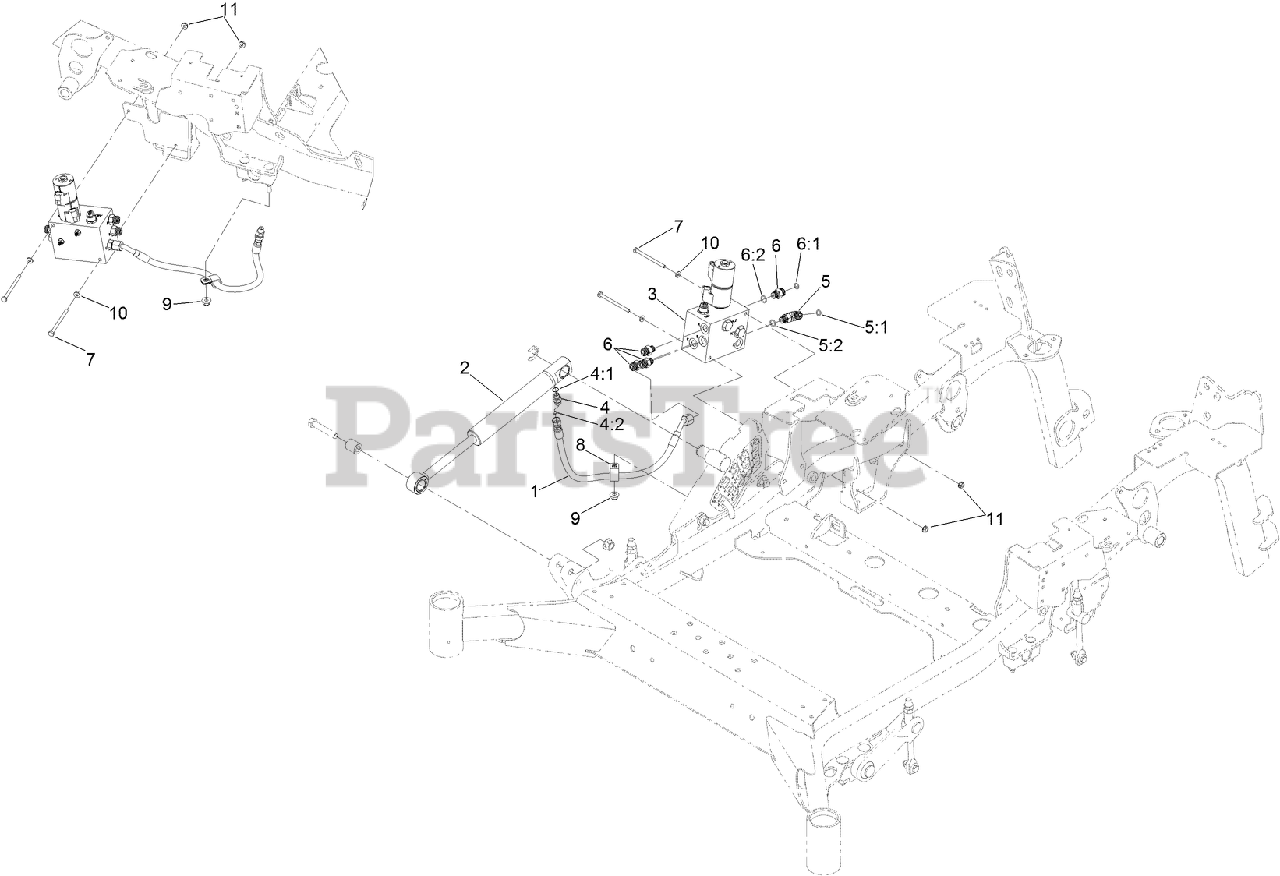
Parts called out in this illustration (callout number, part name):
1	HOSE ASM
2	CYLINDER-LIFT
4	FITTING-HYD, STRAIGHT
4:1	O-RING
4:2	O-RING
5	FITTING-ELBOW, 90 DEG
5:1	O-RING
5:2	O-RING
6	FITTING-STRAIGHT
6:1	O-RING
6:2	O-RING
7	SCREW-HH
8	CLIP-LOOM
9	NUT-HF, NI
10	WASHER-FLAT
11	NUT-HF
